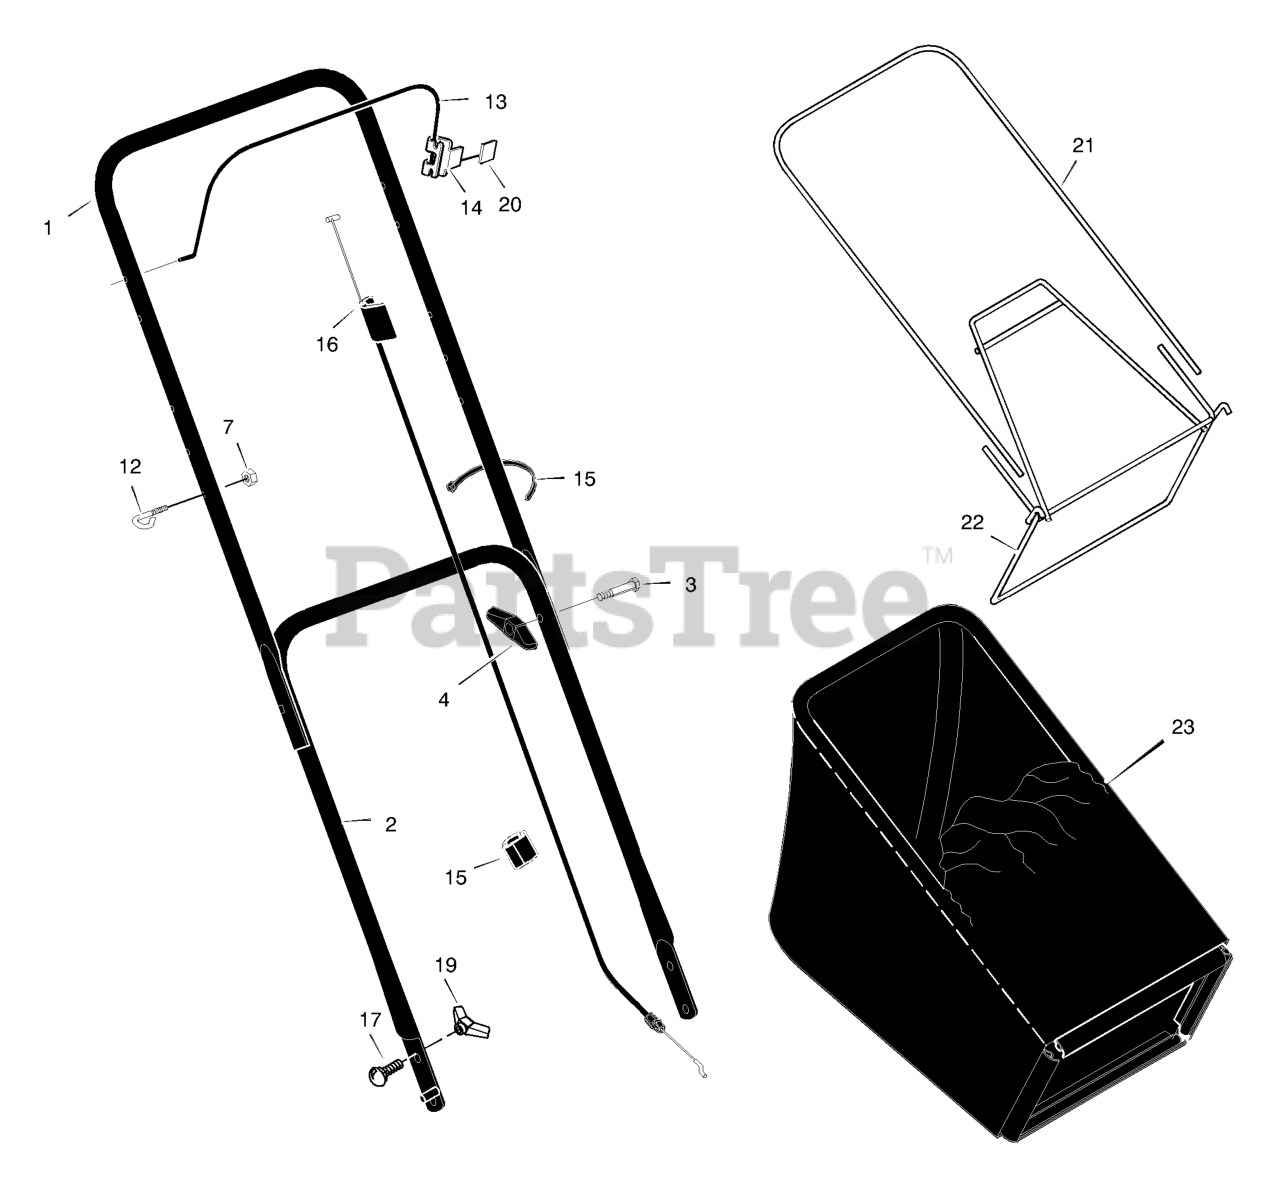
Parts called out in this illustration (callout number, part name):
1	Handle, Upper (Black)
2	Handle, Lower (Black)
4	Knob, Plastic
7	Locknut
12	Guide, Rope
13	Engine Stop Lever
14	Bracket, Stop Lever
15	Clip, Cable
16	Engine Stop Cable
17	Bolt, Carriage
19	Knob, Plastic
20	Sleeve, Vinyl
21	Frame, Top
22	Frame Assembly
23	Bag, Cloth
